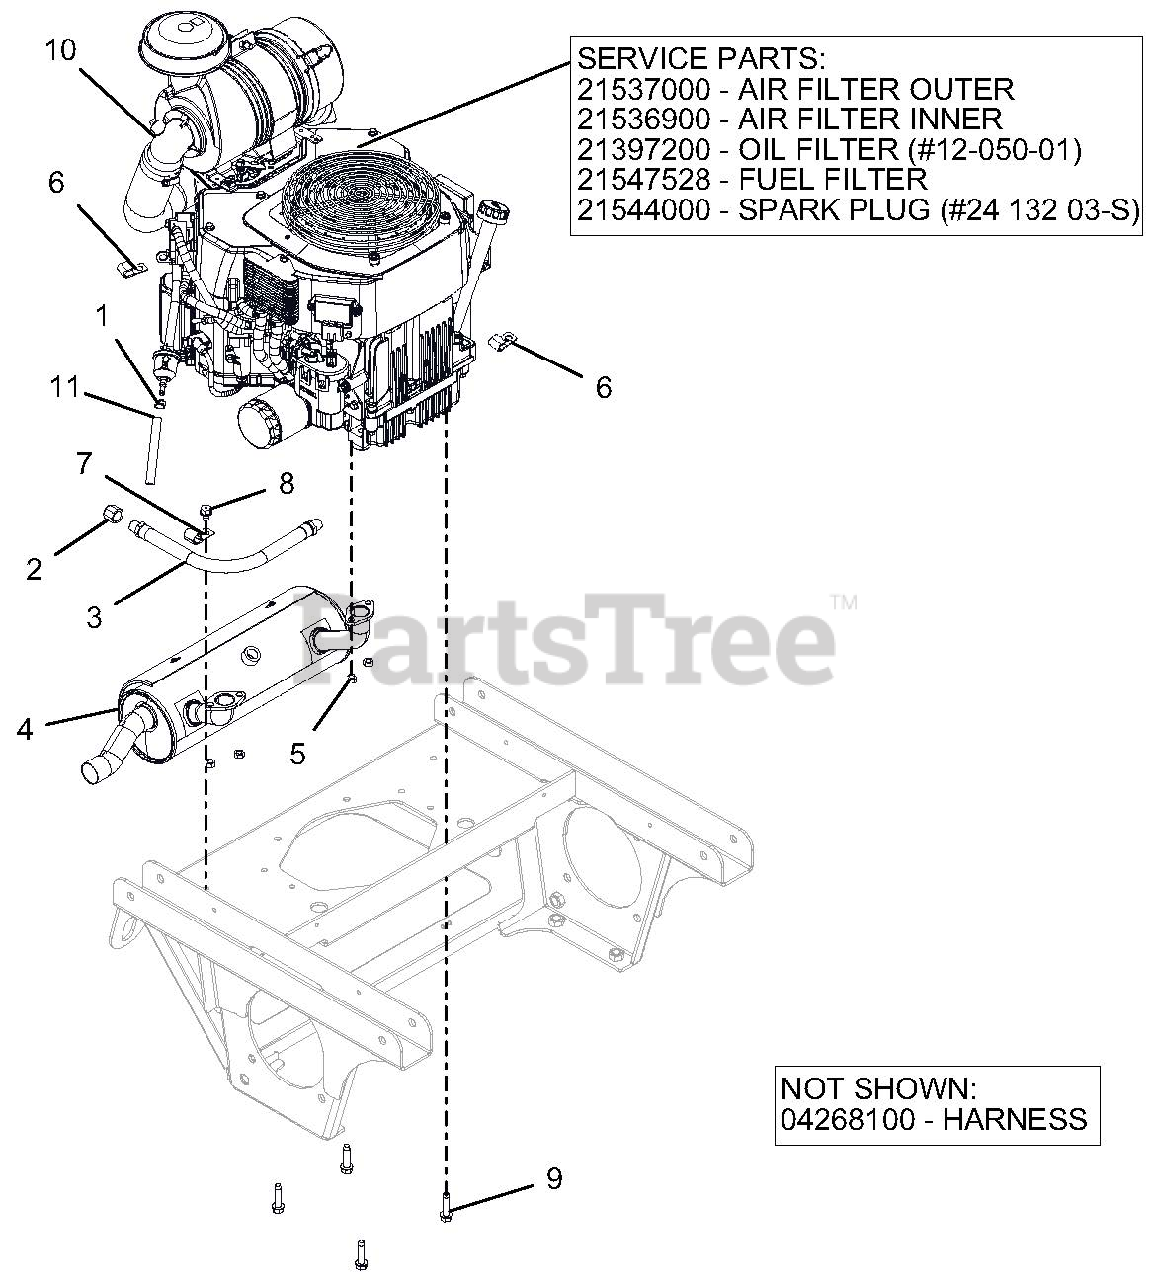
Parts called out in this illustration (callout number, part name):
1	CLAMP, FUEL LINE
2	PIPE, CAP 3/8 NPT FEMALE
3	HOSE, HYD .38-11-OK M6N0-M6N0
4	MUFFLER, KOHLER EFI
5	NUT-LK-TOP M8-1.25 YWZC
6	CLAMP, J
8	SCR-TAP .38-16X.50 HWH TR YWZ
9	SCR-TAP .38-16X1.50 HWH TR YZ
10	ENGINE, KOHLER EFI ECV749
10	AIR FILTER OUTER
10	AIR FILTER INNER
10	OIL FILTER
10	FUEL FILTER
10	SPARK PLUG
11	.25 LOW-PERM GAS HOSE 47.00" LG - VALVE TO ENGINE
